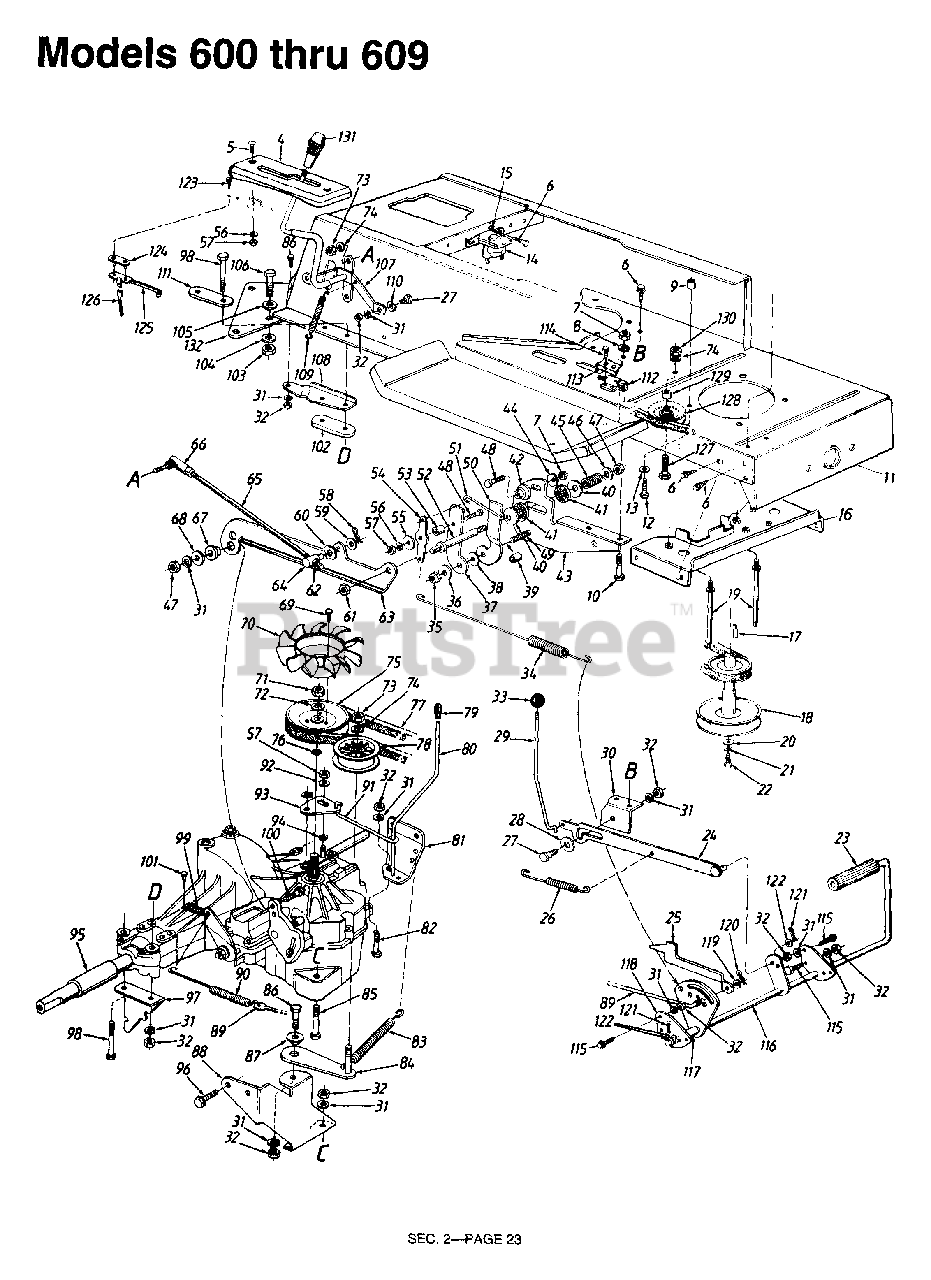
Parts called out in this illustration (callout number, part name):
4	Index Bracket
5	Pan Hd. Mach. Scr. 1/4-20 x .75" Lg.
6	Hex Wash. Hd. TT-Tap Scr. 1/4-20 x .5" Lg.
7	Hex Nut 1/4-28 Thd.
8	L-Wash. 1/4" I.D.
9	Shld. Spacer .38" l.D.
10	Hex. Bolt 1/4-28 x .62" Lg.
11	Lower Frame Ass'y.
12	Hex Tap Scr. 3/8-16 x 1.5" Lg.
13	Fl-Wash. .406" I.D. x 1.25"
14	Solenoid
15	Ext. L-Wash. 1/4" I.D.
16	Belt Guard Brkt. Ass'y.
17	Sq. Key 1/4" x 2" Lg.
18	Engine Pulley
19	Belt Guard Stud 3.6" Lg.
20	Fl-Wash. 7/16" I.D. x 1.25" O.D.
21	L-Wash. 7/16" I.D.
22	Hex Bolt 7/16-20 x 1.5" Lg.
23	Foot Pad
26	Foot Pedal Return Spring
27	Shld. Bolt .437" Dia. x .268"
28	Fl-Wash. 7/16" I.D. x 1-3/8" O.D.
29	Lock-up Rod
30	Bracket
31	L-Wash. 5/16" I.D.
32	Hex Nut 5/16-18 Thd.
33	Ball Knob
34	Neutral Return Spring
35	Hex Nut 5/16-24 Thd.
36	Fl-Wash..344" I.D. x 1" O.D.
37	Scissor-Flat
38	Fl-Wash. .33" I.D. x 1.25" O.D.
39	Spacer
40	Bell-Wash. .4" I.D. x 1.13" O.D.
41	Friction Washer
42	Centering Gauge Spacer
43	Neutral Return Mtg. Brkt.
44	Bell-Wash. .265" I.D. x.75" O.D
45	Comp. Spring 1.19" Lg.
46	Fl-Wash. .312" I.D. x.75" O.D
47	Hex Nut 5/16-24 Thd.
48	Hex Bolt 1/4-28 x 1" Lg. (Gr 5)
49	Rib Neck Bolt 5/16-24 x .84" Lg.
50	Scissor-Offset
51	Neutral Return Rod
52	Friction Disc Stud
53	Shld. Spacer
54	Neutral Return Lever
55	Fl-Wash. .265" I.D. x 1" O.D.
56	L-Wash. 1/4" I.D.
57	Hex Nut 1/4-20 Thd.
58	Hairpin Clip
59	Fl-Wash. .375" I D. x .87" O.D.
60	Spring Wash. .39" I.D.
61	Hex L-Nut 3/8-24 Thd.
62	Hex Jam Nut 3/8-24 Thd.
63	Neutral Return Brkt.
64	Ferrule 3/8-24 Thd.
65	Control Rod
66	Ball Joint 3/8-24 Thd.
67	Shld. Spacer 5" Dia. x .27" Lg.
68	Fl-Wash. .349" I.D. x .879" O.D.
69	Hex Wash. Hd. Tap Scr. #12 x 3/8" Lg.
70	Fan
71	Hex Nut 1/2-20 Thd.
72	L-Wash. 1/2" I.D.
73	Hex Nut 3/8-24 Thd.
74	L-Wash. 3/8" I.D.
75	Transmission Pulley
76	Wire Ring
77	"V"-Belt
78	Fl-Idler Pulley 2.75" O.D.
79	Rod End Grip
80	Bypass Control Lever
83	Ext. Spring 6.12
86	Hex Bolt 5/16-18 x .75" Lg. For
87	Shld. Spacer .5" Dia. x .27" Lg.
88	Transaxle Support Brkt.-R.H.
89	Brake Rod 24.94" Lg.
90	Ext. Spring
91	Bypass Actuator Rod
92	Fl-Wash. .281" I.D. x .5" O.D.
93	Bypass Adjustment Brkt.
94	External L-Wash. 1/4" I.D.
95	Sleeve .758" I.D. x 1" O.D.
96	Hex. Wash. TT-Tap Scr. 5/16-18 x .62" Lg.
99	Tension Spring
100	Hex Bolt 5/16-24 x 1" Lg. (Special)
101	Hex Wash. Hd. AB-Tap Scr. #10 x .5" Lg.
102	Transaxle Spacer
103	Hex Nut 7/16-14 Thd. (Gr. 5)
104	Fl-Wash. .469" I.D. x .875" O.D.
105	Bell-Wash. .46" I.D. x 1.13" O.D.
106	Hex Bolt 7/16-14 x 1" Lg.
107	Speed Control Lever Ass'y.
110	Spr-Wash. .445" l.D. x .75" O.D.
112	Safety Switch (Clutch)
113	Switch Plate
114	Truss Mach. B-Tap Scr. #10 x .5" Lg.
115	Hex Wash. TT-Tap Scr. 5/16-18 x .75" Lg.
120	Cotter Pin 3/32" Dia.
121	Cotter Pin 1/8" Dia.
122	Fl-Wash. .64" I.D. x .94" O.D.
123	Hex Wash. Hd. AB-Tap Scr. #8 x .5" Lg.
124	Insulator Nut Plate
125	Reverse Safety Switch
126	Extension Wire
127	Hex Bolt 3/8-16 x 1.5" Lg. (14 H.P. OHV Only)
128	Idler Pulley (14 H.P. OHV Only)
129	Fl-Wash. .39" I.D. (14 H.P. OHV Only)
130	Hex Nut 3/8-16 Thd.
131	Shift Knob
132	Hitch Plate Extension
